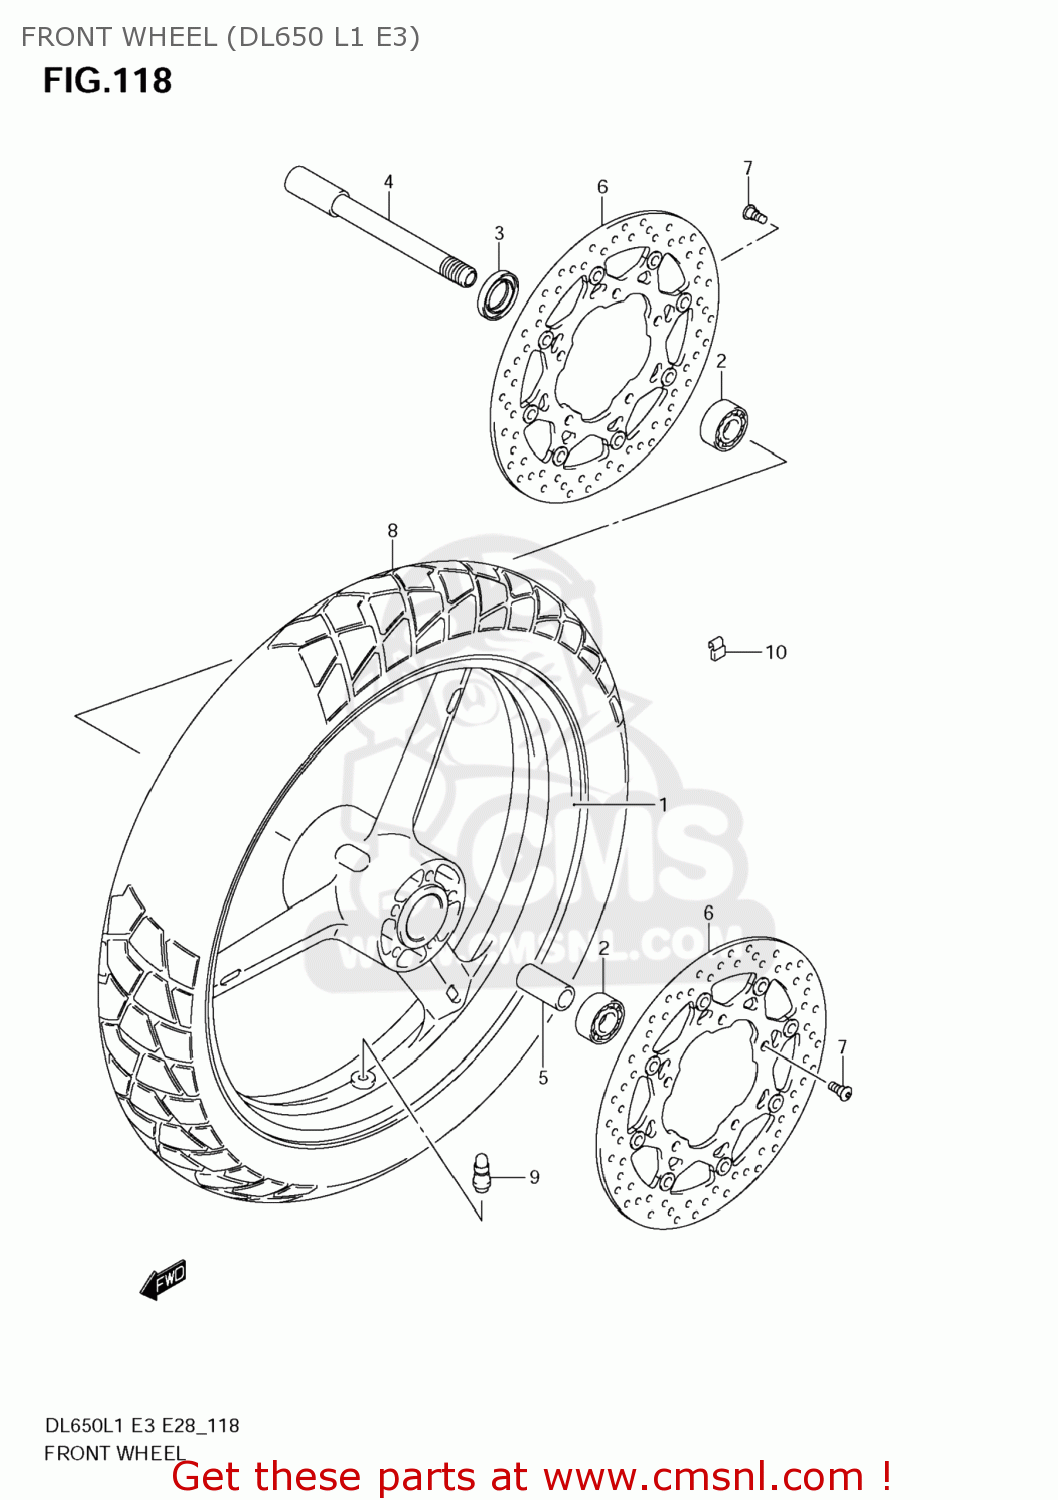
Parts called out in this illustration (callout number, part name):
1	WHEEL,FR(19M/C
2	BEARING
3	SEAL,OIL(22X40X7)
4	AXLE,FR
5	SPACER(17.5X25X88)
6	DISC,FR BRAKE
7	BOLT(8X21)
8	TIRE,FRONT,110
9	VALVE ASSY,WHEEL RIM(TR412)
10	WEIGHT,WHEEL BALANCE 10G
